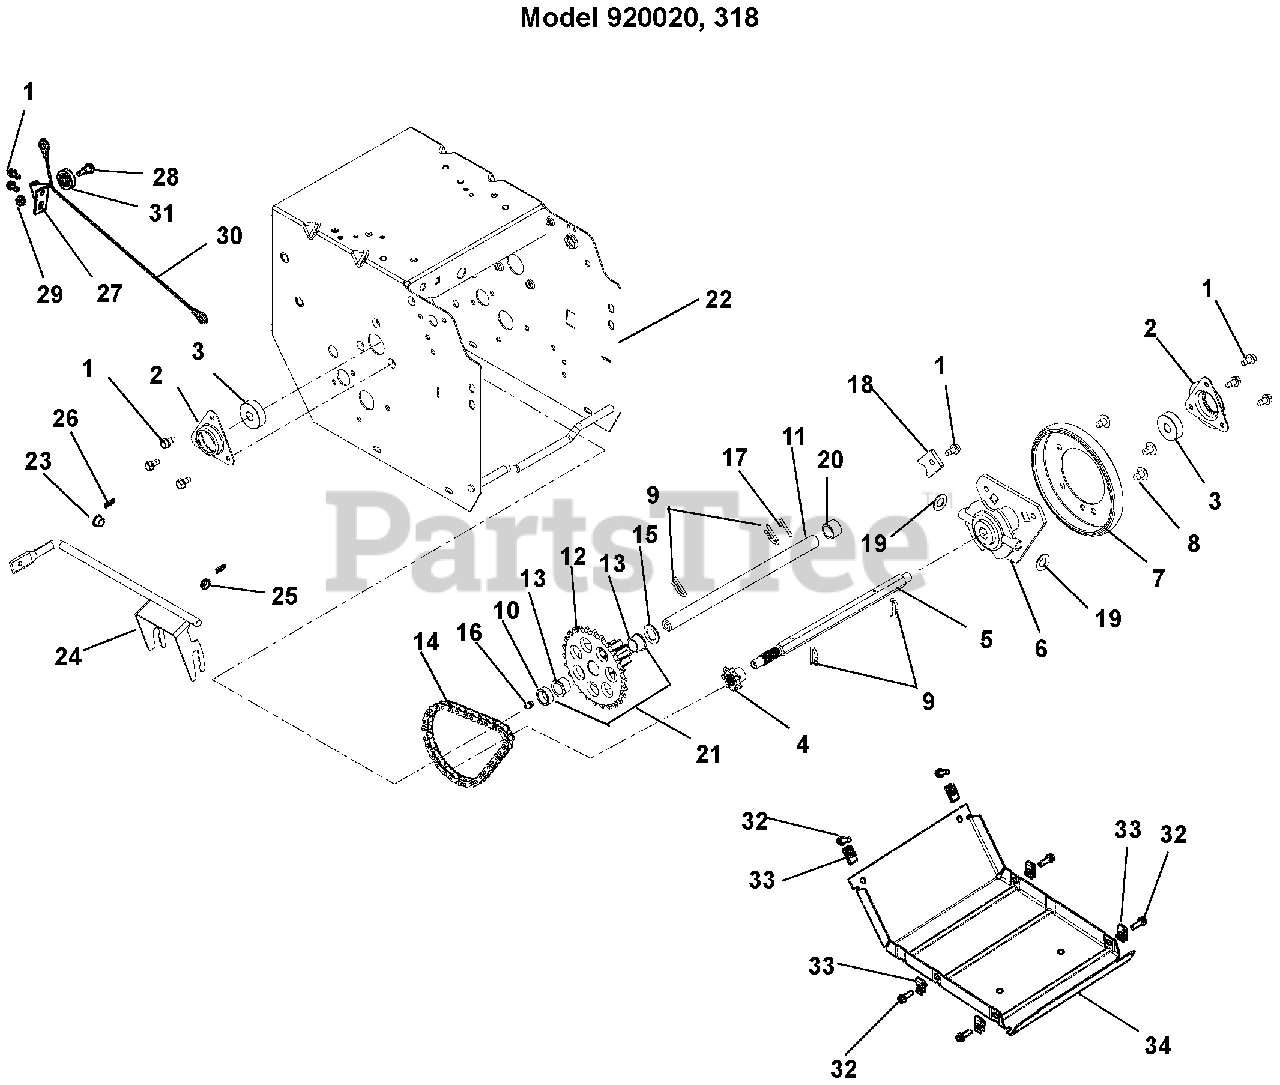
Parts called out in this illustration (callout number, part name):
1	SCR-TAP .25-20X.50 HWH TR YWZ
2	FLANGE, BEARING
3	BRG-BALL .437X1.375X.437
4	SPROCKET, PINION 7T W/SPLINE
5	SHAFT, HEX W/SPLINE TRACK
6	CARRIER, DRIVE DISK
7	FRICTION, DISC
8	SCR-TAP SERRDHDTX .31-18X.50BP
9	PIN, SPRING CLIP
10	BSHG-SLV, .635X.880X.305
11	SHAFT, PINION TRACK
12	PINION & SPROCKET
13	BSHG-FLG .625X.750X.500X.875
14	CHAIN - #41, 32 PITCHES
15	WSHR-FL-STL .630X1.005X.062 YZ
16	ZERK,FITTING .25X.125 DRIVE IN
17	@PIN-GRV .125X1.00 TP E ALLOY
18	TAB, ANTI ROTATION
19	WSHR-FL-STL .505X1.00X.062YWZC
20	SPACER, .635X.880X.611
21	PINION & SPROCKET W/BUSHINGS
22	FRAME, 920/921
23	BUSHING, POLYLINER-.50 SPLIT
24	WELDMENT, SHIFT FORK
25	BUSHING, POLYLINER-.50 SNAPIN
26	CLIP, SPRING
27	BRACKET, CABLE PULLEY
28	BOLT, SHLDR-.375X.375X.25-20
29	@NUT-LK-CTR-FLG .25-20 YWZC
30	CABLE, LOWER TRACTION (CMPCT)
31	PULLEY, CABLE
32	BLT-HEX .25-20X.75 HWH YZ GR5
33	NUT-RTNR .25-20X.56
34	COVER, BOTTOM
